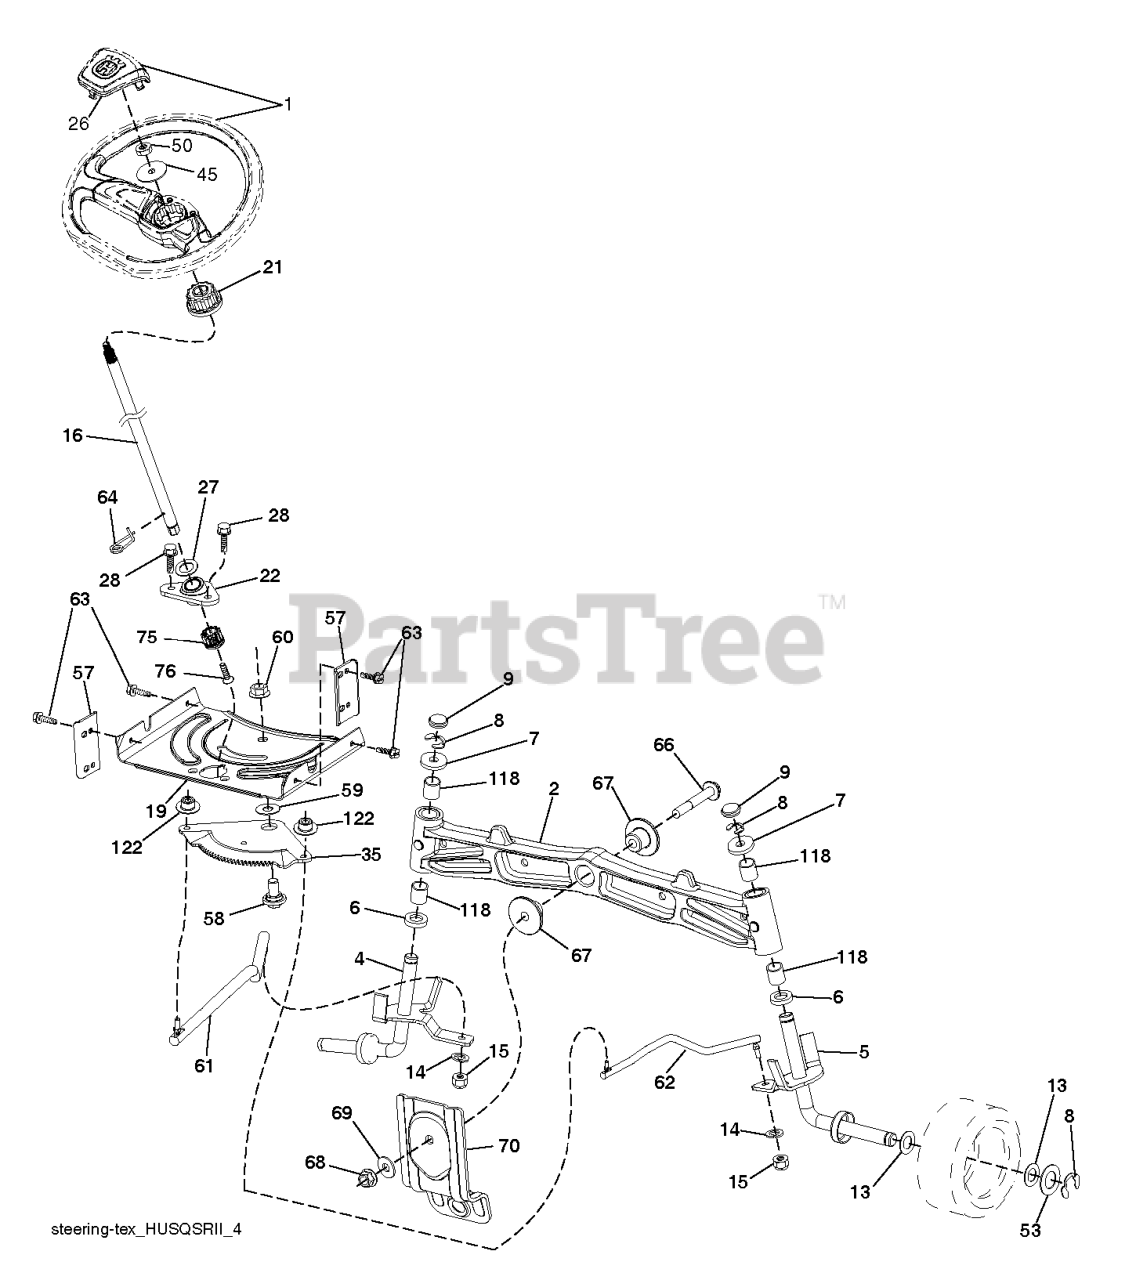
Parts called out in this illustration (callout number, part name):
1	Service Kit
2	AXLE.SVC.ASM CAST IRON.TEX
4	SPINDLE.WELDED.LH.15"TEX
5	SPINDLE.WELDED.RH.15"T
6	WASHER THRUST
9	CAP.SPINDLE.BLACK
15	NUT CROWNLOCK 3/8-24
16	SHAFT.STEER.2HIGH.SPLND.PLATED
19	PLATE.STEER.DDL.NLT/NG
21	ADAPTER.WHEEL.STEER.SPLND.ALUM
22	BEARING.SHAFT.STEER.LOWER.625
28	SCREW, 3/8-16X3/4
35	GEAR.SECTOR.PLATE.DDL.
45	WASHER.3/8ID.2-3/8OD.12GA.PLTD
50	NUT LOCK FLG 3/8-16 UNC
53	WASHER.HARDENED
57	BRACKET.UPSTOP.TEX
58	BOLT.SHOULDER.SECTOR.P
59	WASHER.THURST.SECTOR.S
60	NUT FLANGE LOCK 5/8-11
61	Links
62	Links
63	SCREW
64	RETAINER.CLIP.SPRING.S
66	BOLT HEX FGHD 7/16-14 X 3 SERR
67	BUSHING.PM.FRONT AXLE
68	NUT.LOCK.FLANGE.7/16
69	WASHER.1.5X.505X.118
70	BRACKET.FRT.DECK.SUSP.RR.MT431
75	PINION.ZINC PLATED
76	SCREW HEAD SOCKET LRVB
118	BUSHING, AXLE CAST
122	CAP.GEAR.SECTOR.TEX
